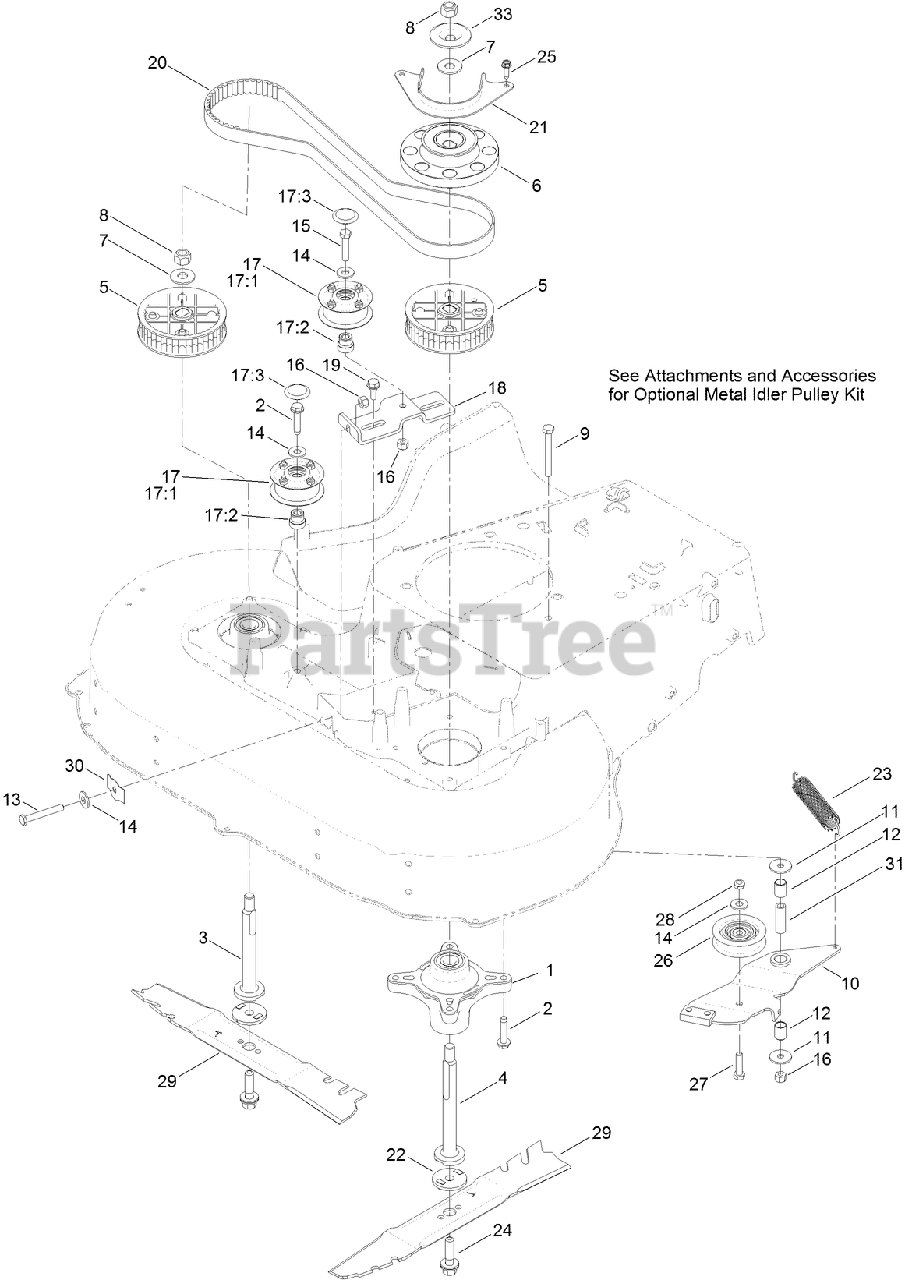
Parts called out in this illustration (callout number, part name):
1	SPINDLE ASM
3	SHAFT-SPINDLE
4	SHAFT-SPINDLE
5	SPROCKET
6	PULLEY-BRAKE, SPINDLE
7	WASHER-SPRING
8	NUT-HEX
9	SCREW-HH
10	BRAKE ARM ASM
11	WASHER-PIVOT
12	Bushing-Sleeve
13	BOLT-TAP, HH
14	WASHER-FLAT
15	SCREW-HH
16	NUT-LOCK, NI
17	PULLEY KIT
17:1	PULLEY ASM
17:2	ADAPTER-BORE
17:3	PLUG-CAP
18	BRACKET-IDLER
19	SCREW-SHOULDER, HHF
20	BELT-SYNCHRONOUS
21	GUIDE-BELT, SPINDLE
22	ADAPTER-BLADE
23	SPRING-EXTENSION, BRAKE
24	BOLT-BLADE
25	SCREW-HWHTF
26	PULLEY-IDLER
27	SCREW-HH
28	NUT-LOCK, NI
29	BLADE-ROTARY
30	SPRING-FLAT
31	Spacer-Brake
33	WASHER-CUP
